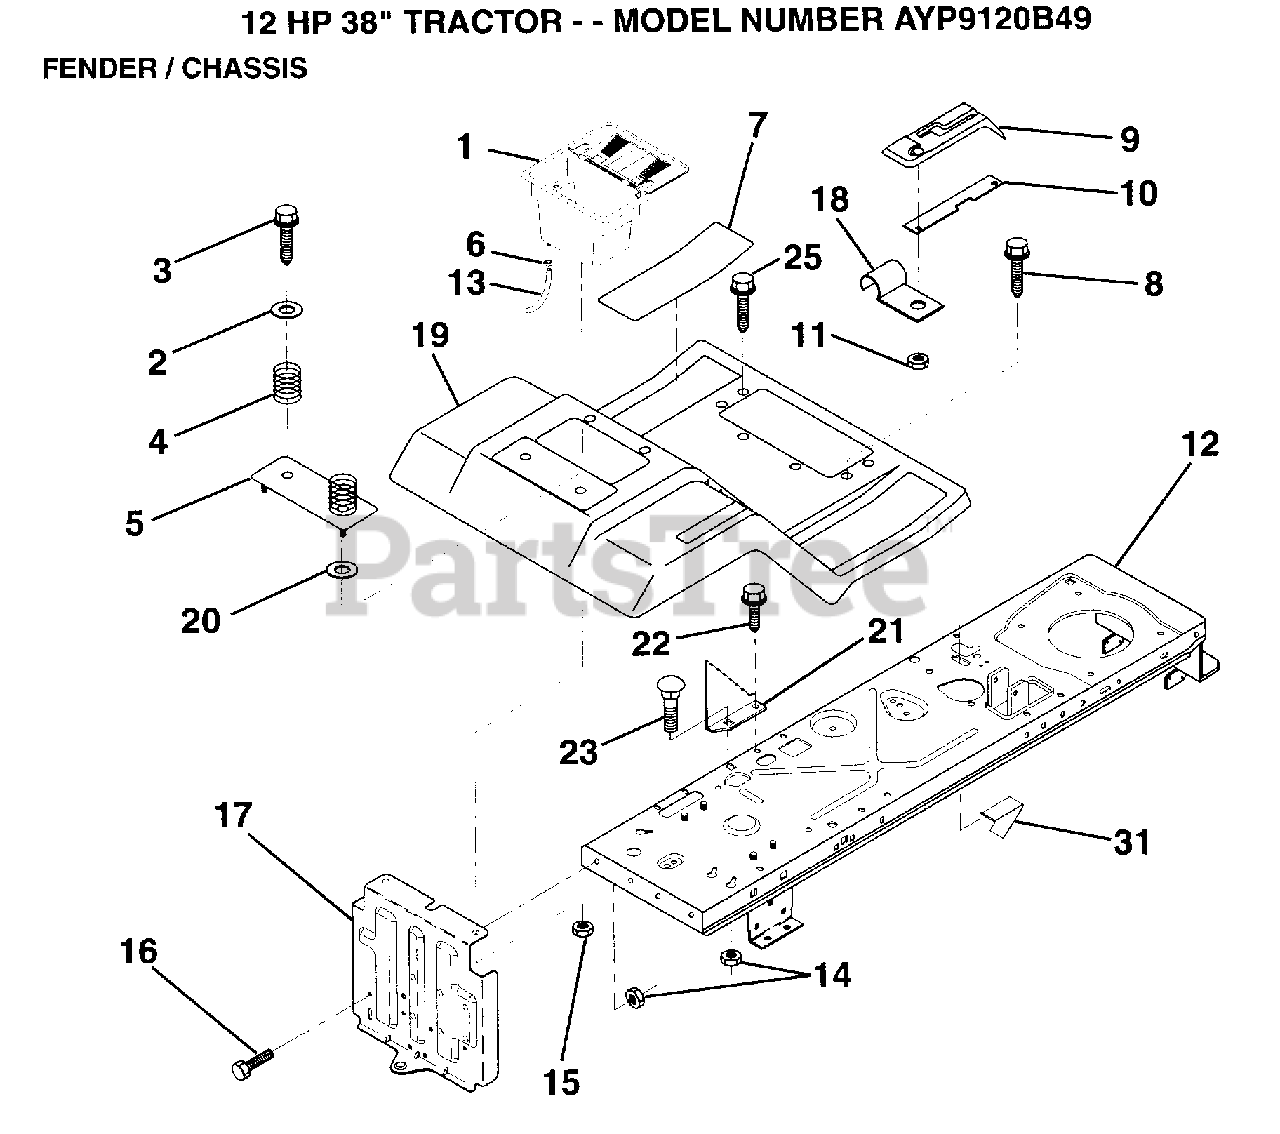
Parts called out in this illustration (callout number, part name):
2	WASHER
3	SCREW
4	SPRING COMPRESSIO
5	BTRY FENDER PLATE
6	HOSE CLAMP T
7	PAD FOOTREST
8	SCREW
9	CONSOLE SHFT 4SP
10	PLATE LOCK SHIFT
11	NUT
13	TUBE T
14	NUT
15	NUT
16	BOLT
17	DRAWBAR ASM LR
18	"CLIP,INSULATOR"
19	FENDER/FOOT MS505
21	BRACKET STOP DEPT
22	SCREW LT
25	SCREW TI
